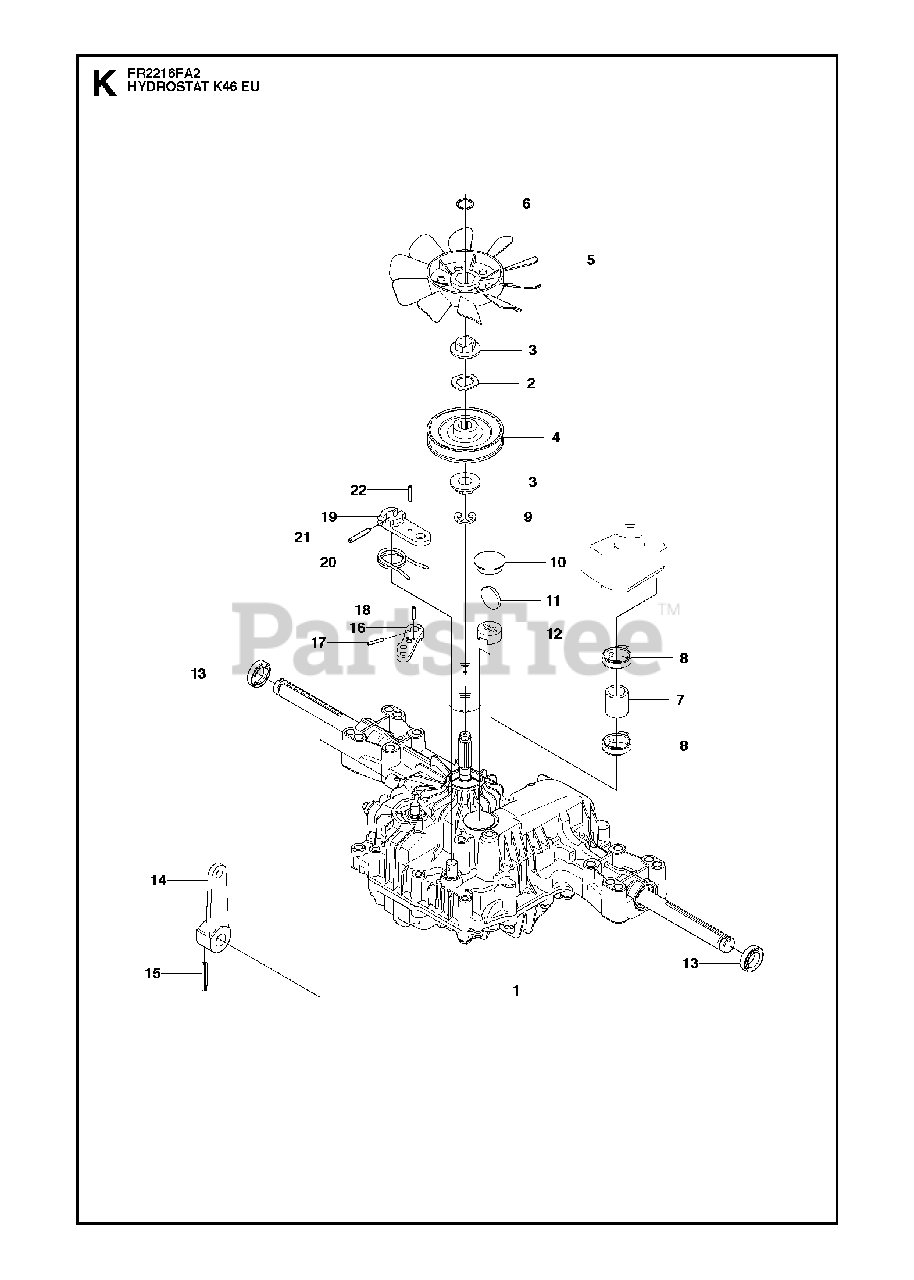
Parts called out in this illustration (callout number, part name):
1	HYDROSTAT
2	WASHER **
5	FAN
6	RETAINING RING **
8	CLAMP
9	CLIP
10	PLUG
11	MAGNET
12	MAGNET HOLDER
13	SEALING
14	CONTROL LEVER
15	PIN
16	ARM
17	PIN
18	PIN
19	ARM
20	RETURN SPRING
21	PIN
22	PIN
